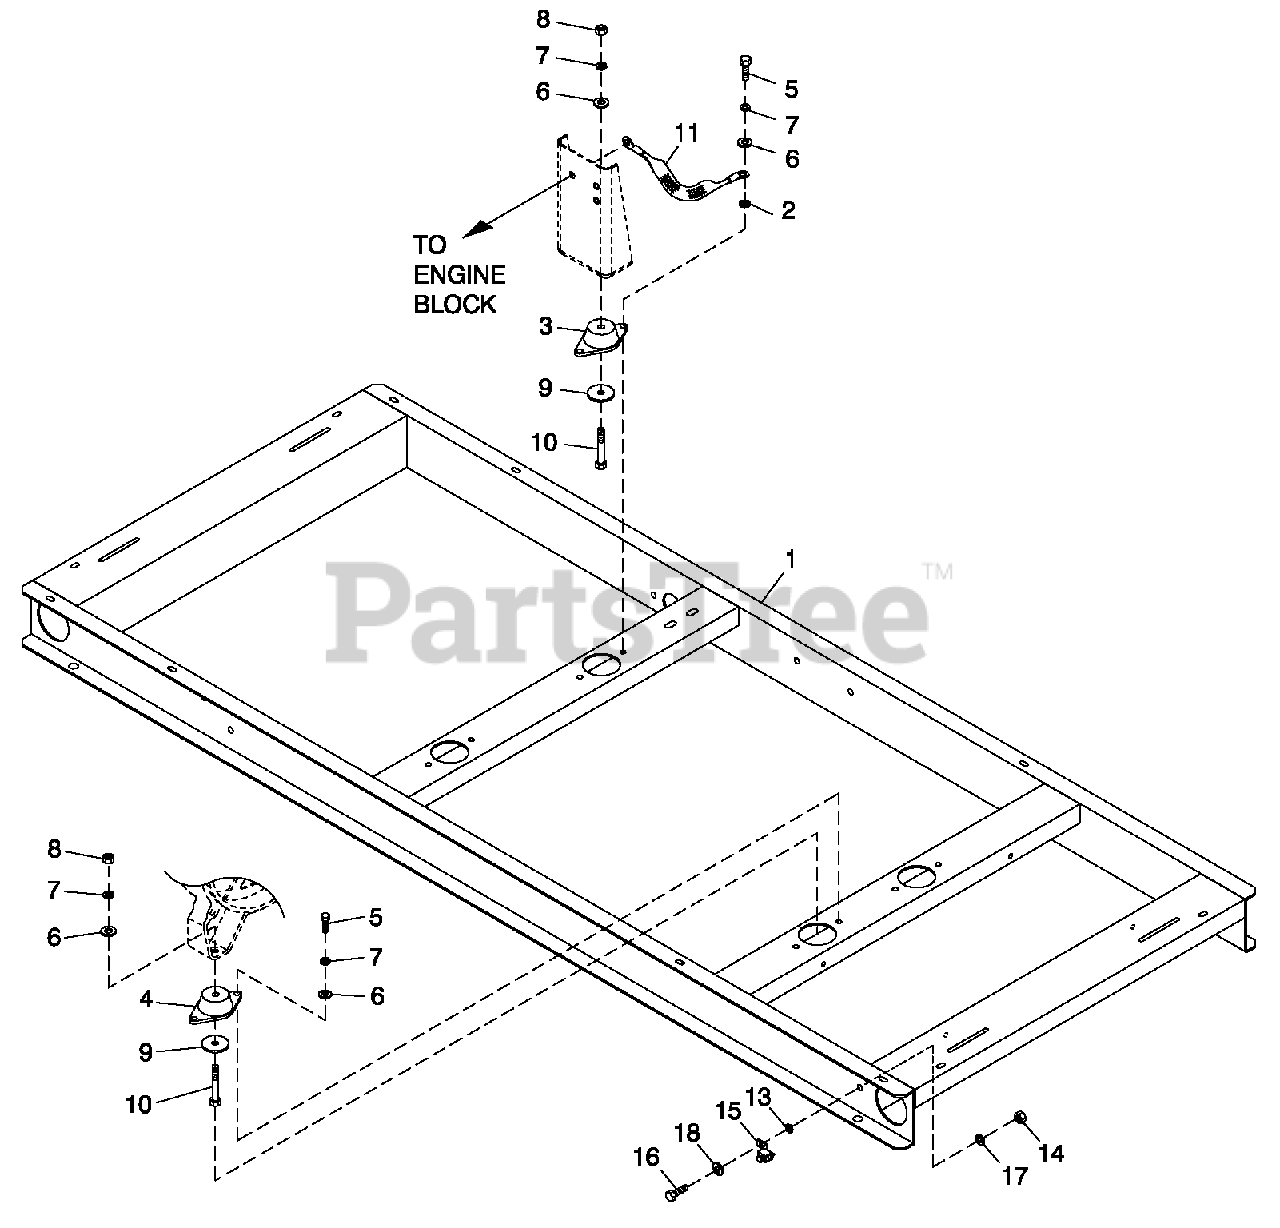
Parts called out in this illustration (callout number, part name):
1	MOUNTING BASE 1.6L
2	WASHER SHAKEPROOF EXT 5/16 STL
3	DAMPENER VIBRATION
4	VIB. ISO. 70-75 DURO
5	SCREW HHC M8-1.25 X 20 G8.8
6	WASHER FLAT 5/16 ZINC
7	WASHER LOCK M8-5/16
8	NUT HEX M8-1.25 G8 YEL CHR
9	WASHER FLAT M8
10	SCREW HHC M8-1.25 X 60 G8.8
11	EARTH STRAP
13	WASHER SHAKEPROOF EXT 1/4 STL
14	NUT HEX M6 X 1.0 G8 YEL CHR
15	LUG SLDLSS #2-#8 X 17/64 CU
16	SCREW HHC M6-1.0 X 16 G8.8
17	WASHER LOCK M6-1/4
18	WASHER FLAT 1/4-M6 ZINC
